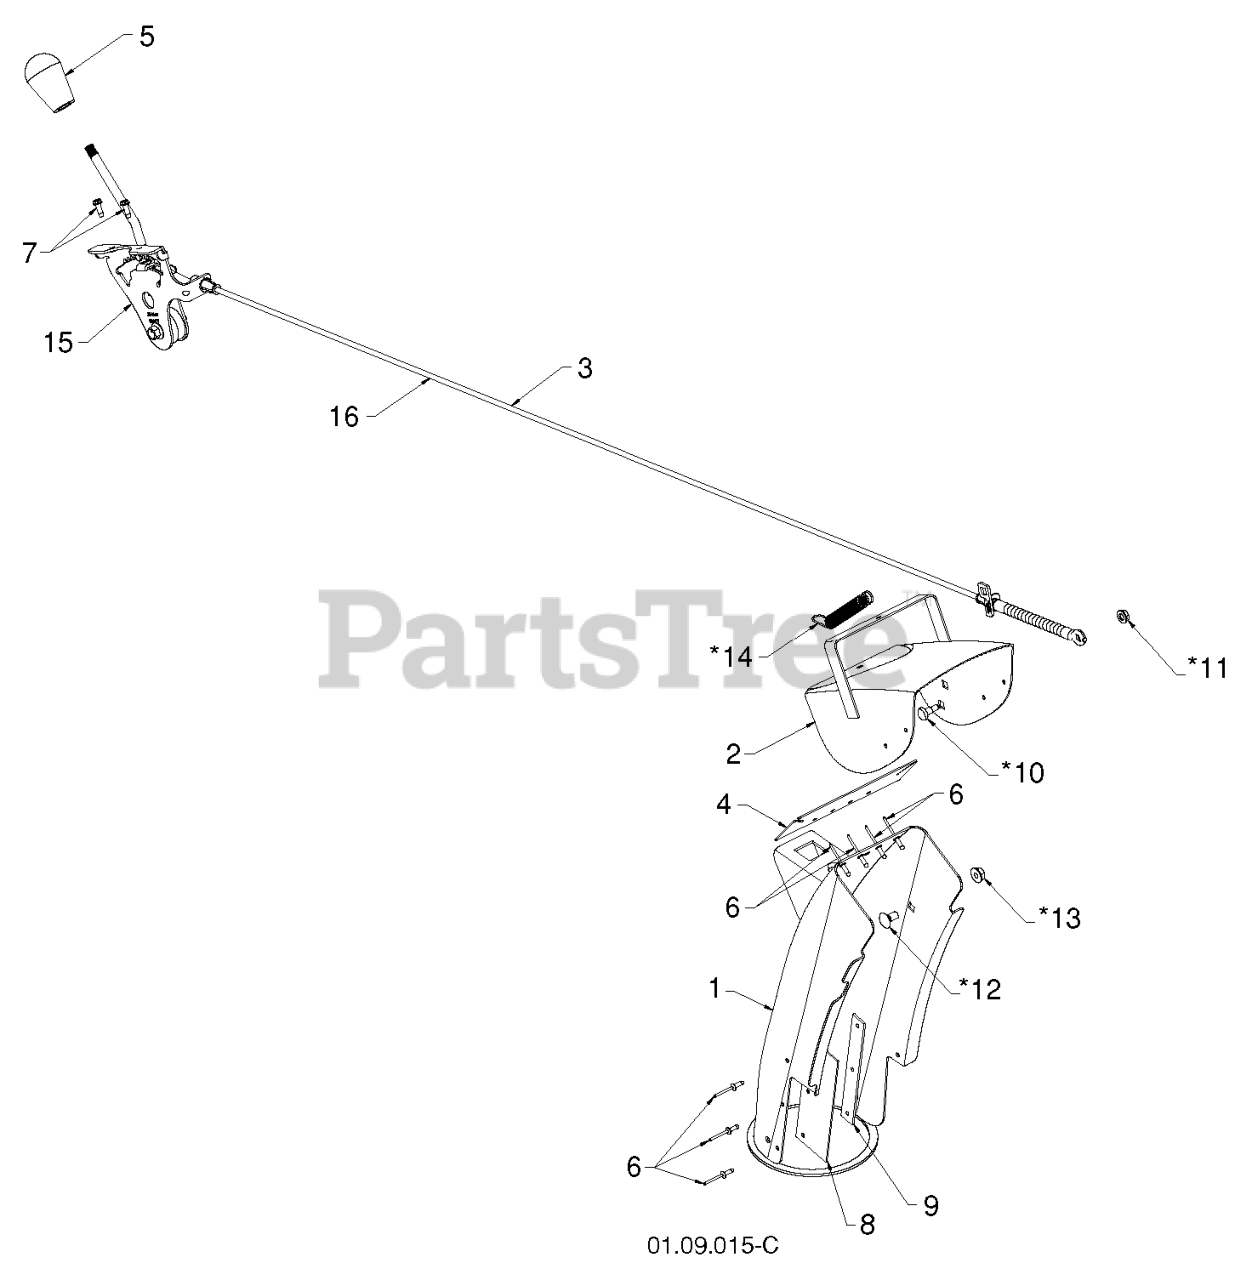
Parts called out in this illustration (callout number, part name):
1	CHUTE.WELDMENT.SNOW.ORANGE
2	DEFLECTOR.WELDMENT.PNT.ORANGE
3	RP.CONTROL.ASM.DEFLECTOR.SNOW
4	SEAL.DEFLECTOR
5	KNOB LEVER, BLACK
6	RIVET BLIND
7	SCREW #10-24 X 5/8
8	SHIELD.SNOW.CHUTE
9	STRAP.SHEILD.RETAINER
10	BOLT, SHOULDER
11	NUT.HEX.FLANGE.1/4
12	BOLT
13	NUT.LOCK.5/16-18
14	SPRING.DEFLECTOR.REM.CHUTE
15	RP CNTRL.HEAD.ASSEM.DEFLECTOR
16	RB SERVICE.CHUTE.DEF.CBL.BLK
